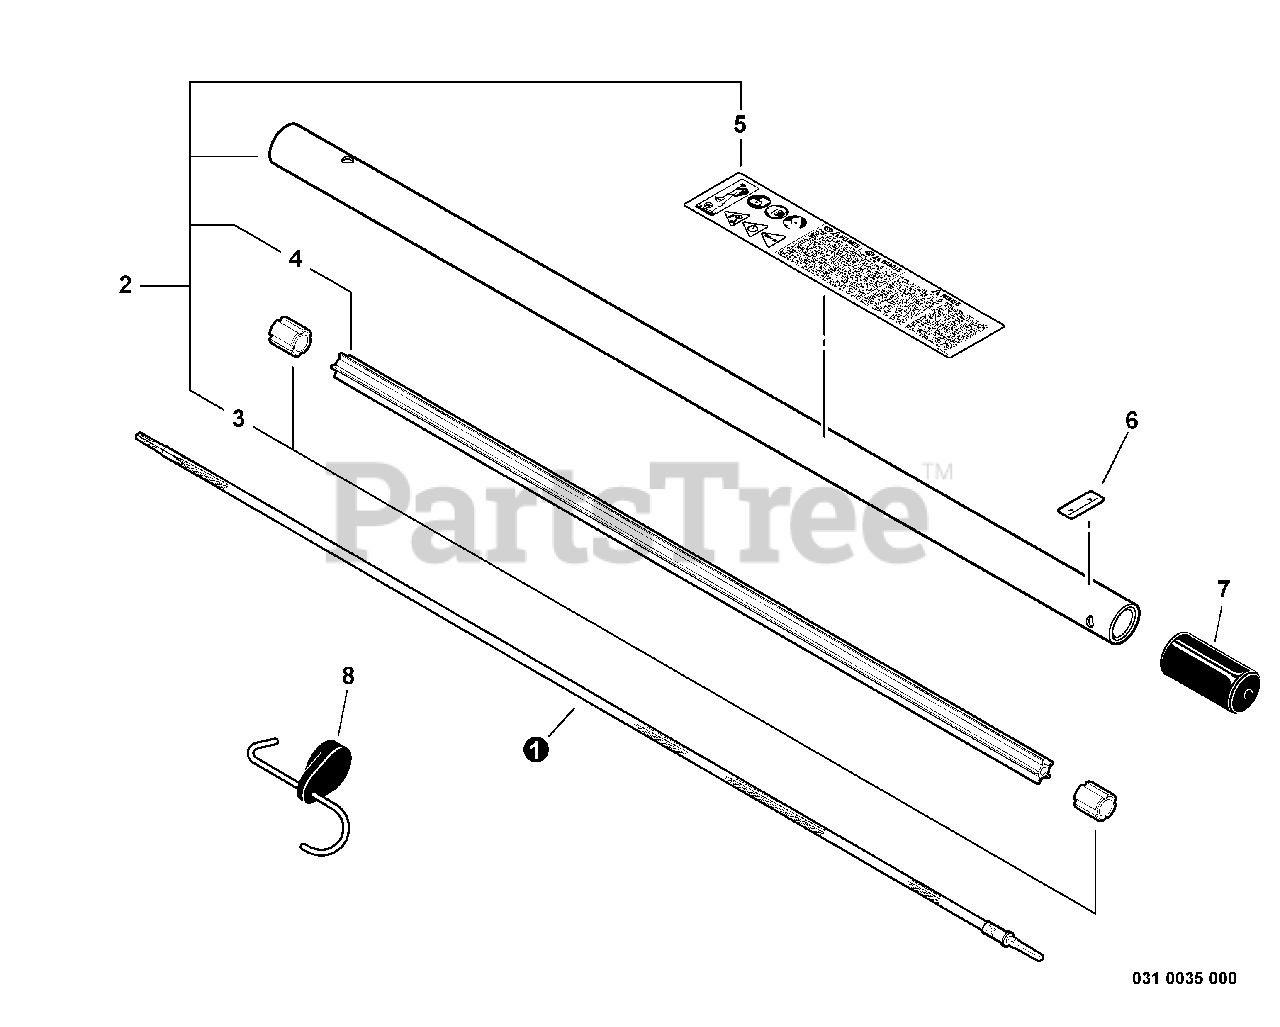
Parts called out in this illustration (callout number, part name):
1	DRIVESHAFT - FLEXIBLE
2	MAIN PIPE ASSY
4	LINER - FLEXIBLE
5	LABEL - CAUTION
7	PAS ATTACHMENT HANGER
8	LABEL - ALIGNMENT
